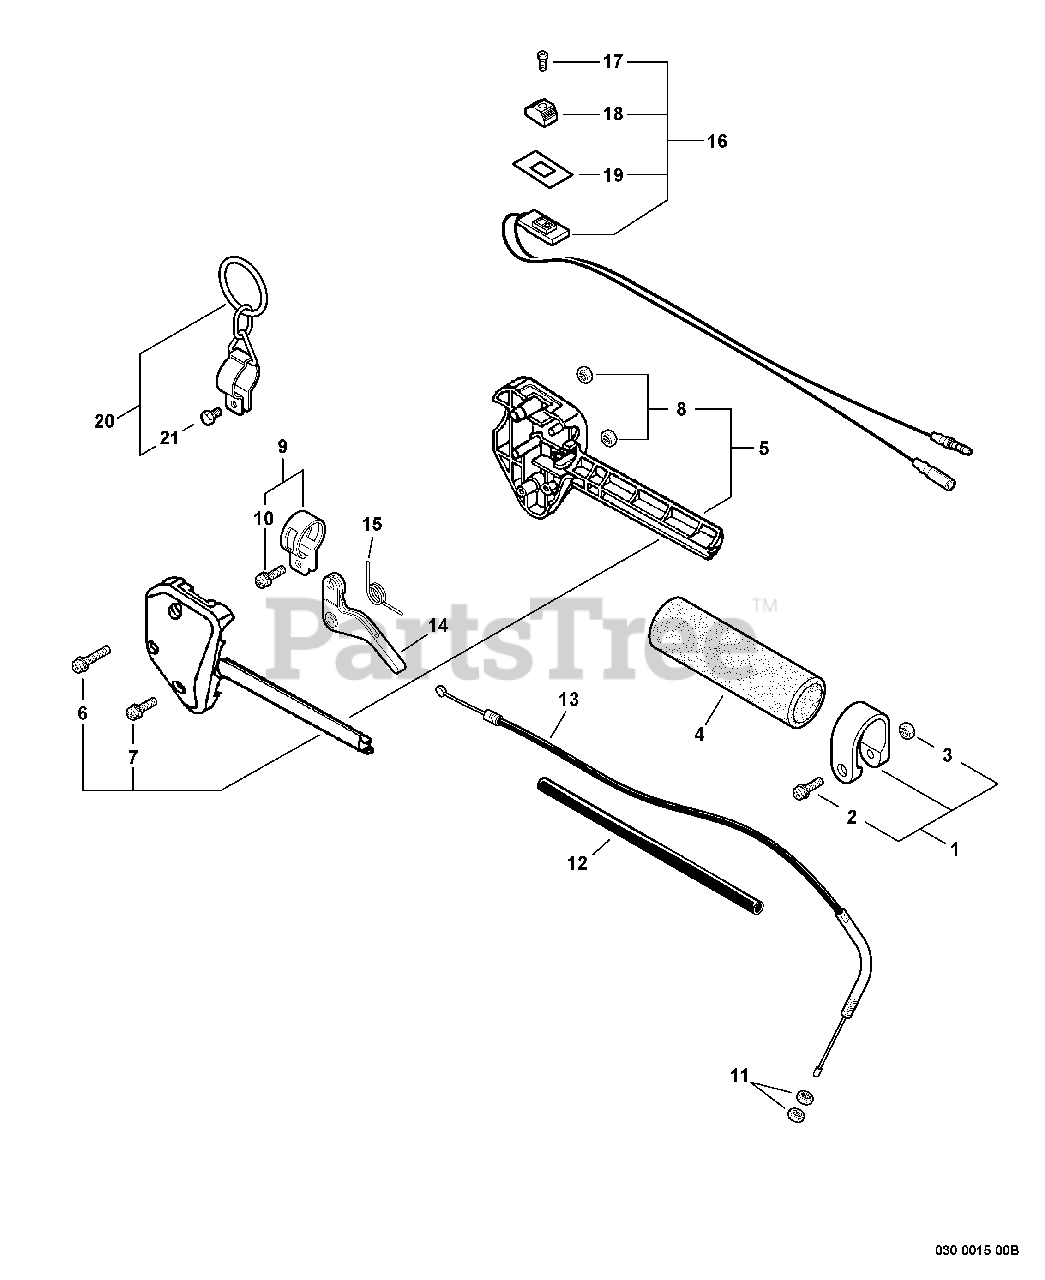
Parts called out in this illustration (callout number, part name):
1	CLAMP KIT
2	SCREW - 5X28
4	GRIP, HANDLE
5	CONTROL HANDLE KIT
6	SCREW - 5X35
7	SCREW - 5X25
9	CLAMP KIT
10	SCREW - 5X14
12	TUBE - VINYL
13	CABLE, THROTTLE
14	TRIGGER, THROTTLE
15	SPRING, TRIGGER
16	IGNITION SWITCH ASSY
17	SCREW - 3X10
18	KNOB, SWITCH - ORANGE
19	COVER, SWITCH - STOP
20	HANGER KIT
21	BOLT - 5X12
